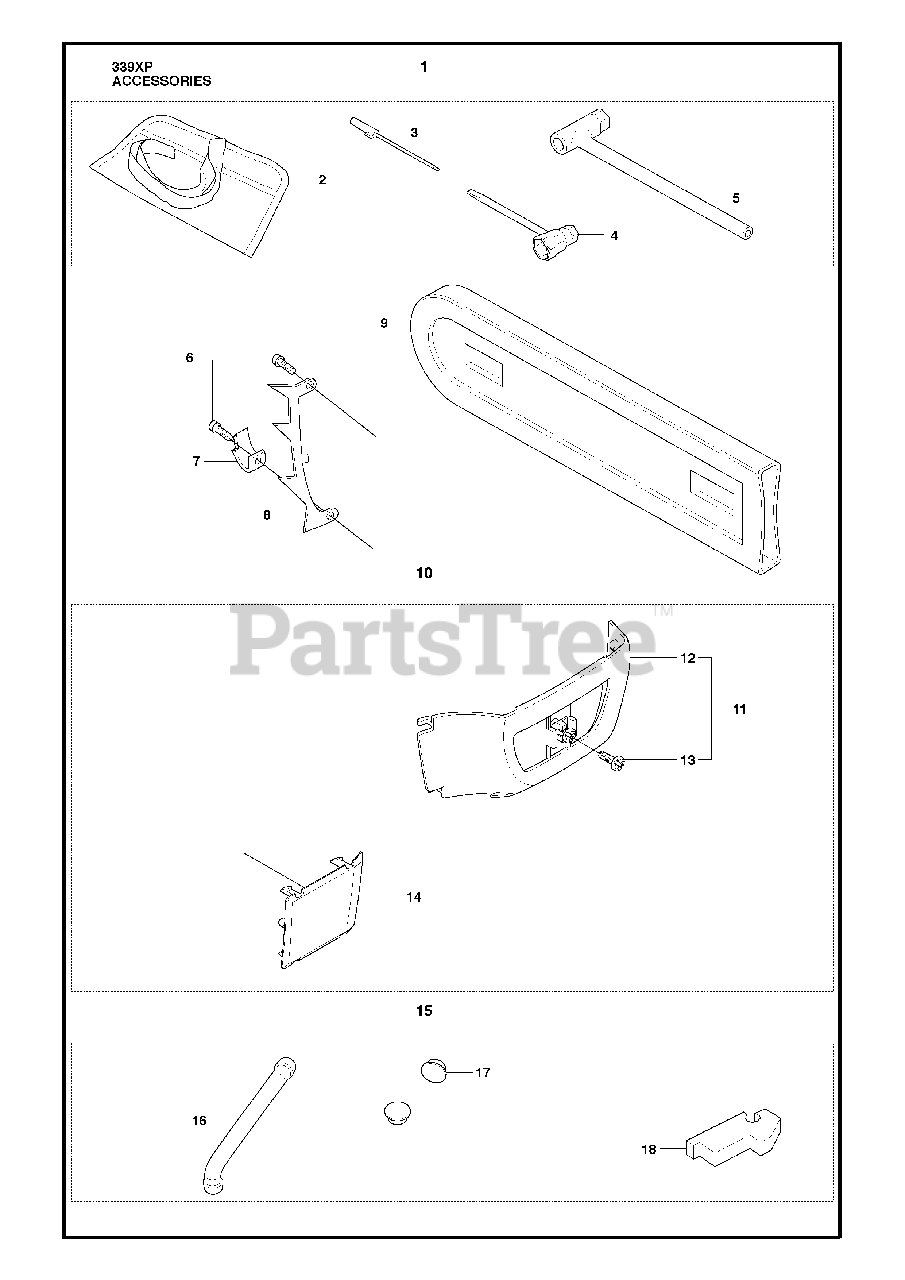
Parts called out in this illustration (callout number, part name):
1	TOOL KIT (3 PC)
3	SCREWDRIVER
4	COMBI TOOL
5	COMBI WRENCH
7	CHAIN CATCHER
8	FELLING DOG
9	Scabbard, 13"-16"
10	WINTER COVER ASSY
11	WINTER COVER ASSY
12	Winter Cover
15	WINTER SET
18	FOAM INSULATOR
